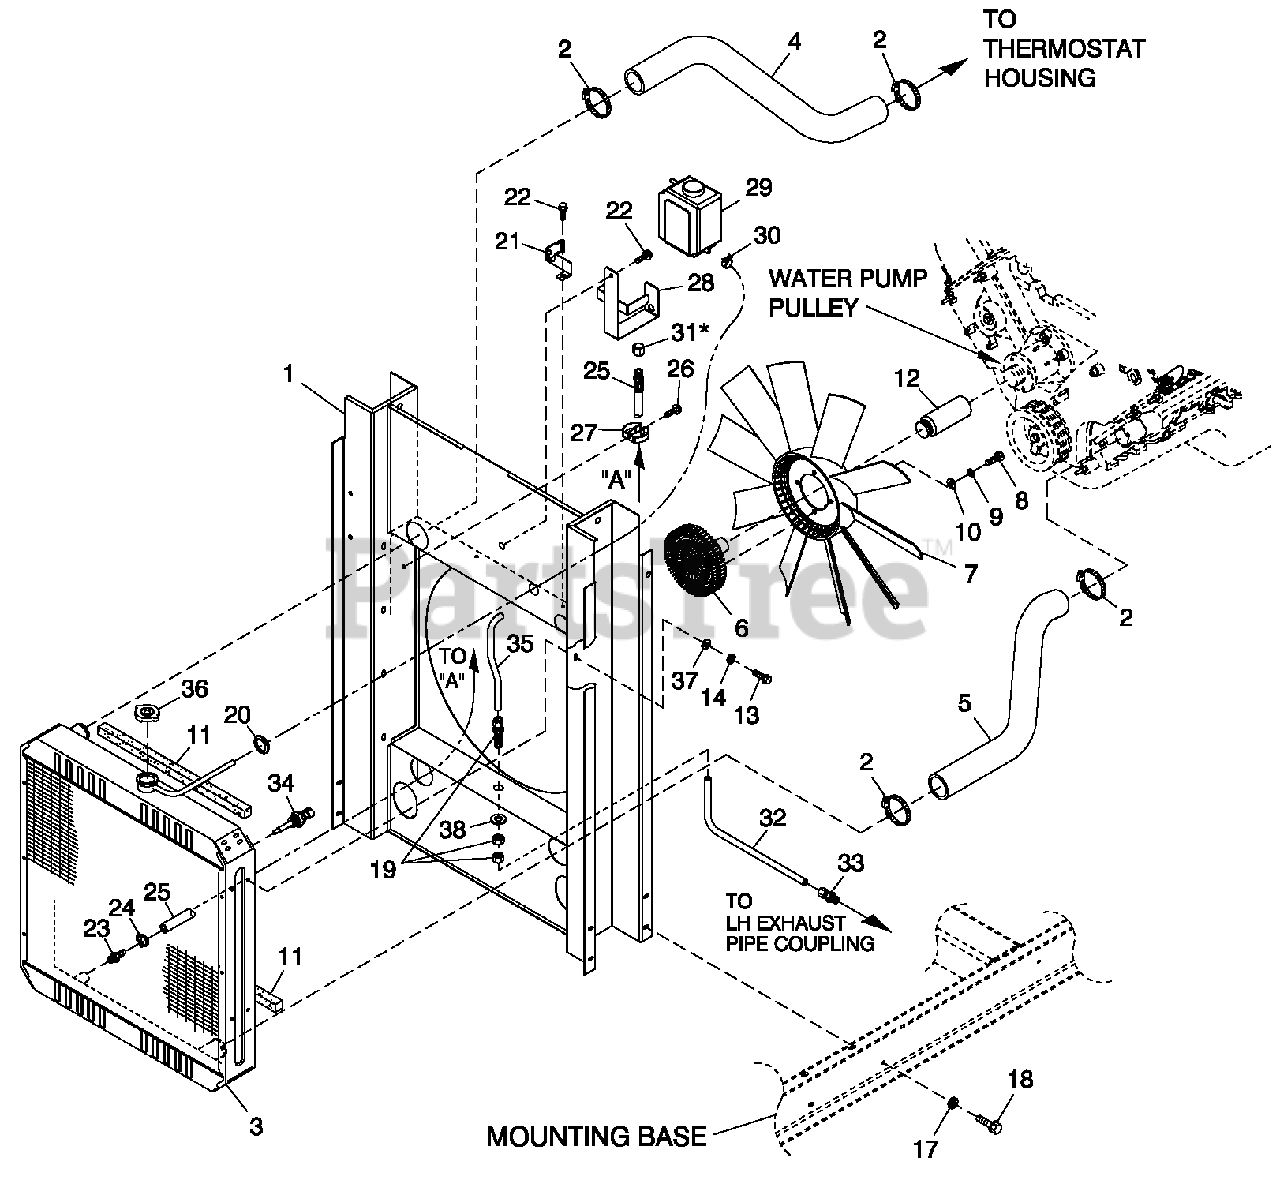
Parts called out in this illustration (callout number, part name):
2	CLAMP HOSE #28 1.32-2.25
3	RADIATOR581X 585 X 70 CPL LH
4	HOSE UPPER RADIATOR C3
5	HOSE LOWER RADIATOR C3
6	CLUTCH COOLING FAN
7	FAN 22" DIA 10 BLADE
8	SCREW HHCM10-1.5 X20G8.8
9	WASHER LOCK M10
10	WASHER FLAT 3/8-M10ZINC
11	TAPE FOAM 1X1 (23" LG)
12	SPACER FAN 6.8L
13	SCREW HHFCM8-1.25 X 20 W/M6
14	WASHER LOCK M8-5/16
17	WASHER LOCK M6-1/4
18	SCREW HHFCM6-1.0X20 G8.8
19	FTG CMPN BLKHD3/8" OD TUBE BRS
20	GROMMET.75X.12X.50
21	BRACKET SIGNAL CONDITIONER
22	SCREWTHF M6-1 X 16 NWAZ/JS
23	BARBED STR 3/BNPTX3/8
24	CLAMP HOSE .38-.87
25	HOSE DRAIN ASSY 28"
26	SCREW HHTT M4-0.7X 8 BP
27	SPRING CLP HOLDER .37-.62
28	BRKT COOLANT RECOVERYTANK
29	TANK COOLANT RECOVERY
30	CLAMP HOSE BAND 1/4
31	CAP HEX 1/4 NPT BRASS
32	TUBE FAN CLUTCH PREHTR LOWR C3
33	FTG CMPR 3/8TUBEX 3/8 NPT W/FERL
34	PROBE COOLANT LEVEL 3/8NPTF (USE WITH HARN P/N 0F5990& 0F5991)
35	TUBE FAN CLUTCH PREHTR UP PR C2
36	CAP RADIATOR 13 PS I
37	WASHER FLAT 5/16-M8ZINC
38	WASHER FLAT 9/16 ZINC
